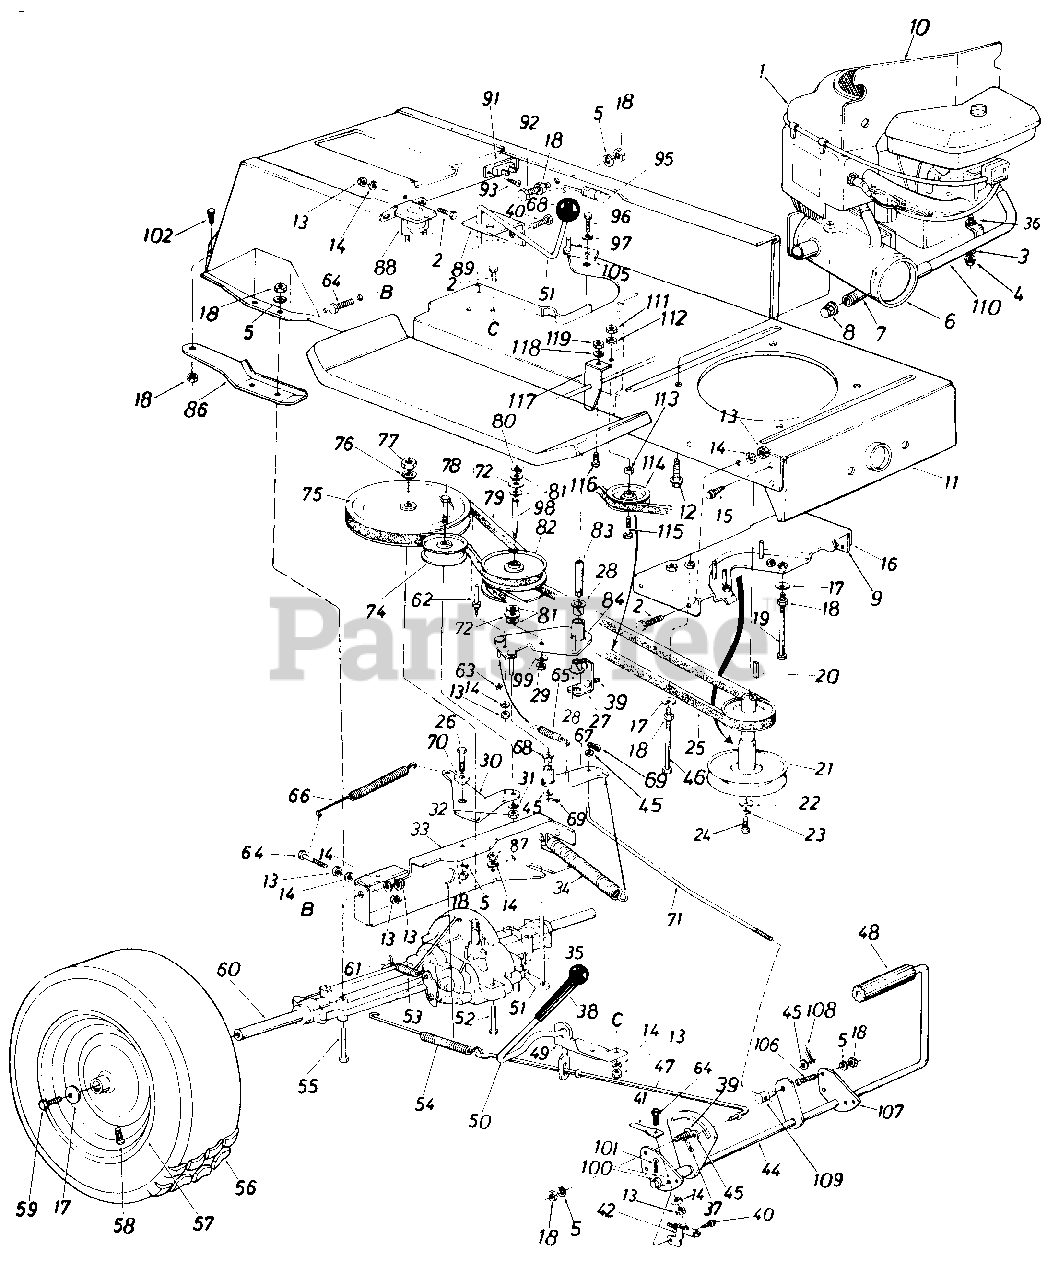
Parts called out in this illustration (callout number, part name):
1	Engine
2	Hex Bolt 1/4-20 x .62" Lg.*
3	Special L-Wash. 5/16" I.D.
4	Hex Nut 5/16-18 Thd.*
5	L-Wash. 5/16" I.D.*
6	Exhaust Muffler
7	Pipe Nipple
8	Cap Oil Drain
9	Brake Cable Brk't.
10	Heat Shield
11	Lower Frame Ass'y.
12	Hex Wash. Hd. TT-Tap Scr. 3/8-16 x 1.25" Lg.
13	Hex Nut 1/4-20 Thd.*
14	L-Wash. 1/4" I.D.*
15	Hex Wash. Hd. AB-Tap Scr. 5/16" x .75" Lg.
16	Belt Guard Brkt. Ass'y.
17	Bell-Wash. .345" I.D. x .88"
18	Hex Nut 5/16-18 Thd.*
19	Hex Bolt 5/16-18 x 4.00"*
20	Sq. Key 1/4 " x 1/4 " x 2.00"
21	Engine Pulley
22	Fl-Wash. 7/16" I.D. x 1.25"
23	L-Wash. 7/16" I.D.*
24	Hex Bolt 7/16-20 x 1.50" Lg.
25	Variable-Speed Belt .715 x 53" Lg.
26	Hex Bolt 5/16-18 x .75" Lg.*
27	Bearing Shaft Bracket
28	Flanged Nyliner Brg. 5/8" I.D. x .88 " Lg.
29	Hex Nut 3/8-24 Thd.*
30	Idler Bracket
31	L-Wash. 3/8" I.D.*
32	Hex Nut 3/8-24 Thd.*
33	Transaxle Support Brkt.
34	Ext. Spring .94" O.D. x 6.7
35	Cotter Pin 1/8" Dia. x 1.0"*
36	Fl-Wash. .34" I.D. x .62" O.D. x .033
37	Cotter Pin 3/32" Dia. x 1.0"*
38	Grip Black
39	Truss Mach. Scr. 5/16-18 x .75" Lg.
40	Hex Wash. Hd. Self-Tap Scr. 1/4-20 x .50" Lg.
41	Switch Actuator
42	Safety Switch
44	Clutch & Brake Pedal Ass'y.
45	Fl-Wash.
46	Hex Bolt 5/16-18 x 4.5"*
47	Brake Rod
48	Foot Pad
49	Brake Lever Bracket
50	Hill Holder Brake Handle
51	Shift Lever Ass'y.
52	Hex Bolt 1/4-28 x 1.75" Lg.*
53	Ext. Spring .38" O.D. x 2.5"
54	Ext. Spring .59" O.D. x 7.08"
55	Hex Bolt 5/16-18 x 2.50"*
58	Air Valve
59	Hex Bolt 5/16-24 x .75" Lg.*
60	Transaxle Complete
61	Brake Return Spring Anchor
62	Belt Guard Pin 1/4-20 Thd.
63	Cap Speed Nut 1/4" Dia.
64	Hex Bolt 1/4-20 x 1.0" Lg.*
65	Ext. Spring .50" Dia.
66	Ext. Spring .56" O.D. x 5.96"
67	Variable Speed Torque Brkt. Ass'y.
68	Flanged Bearing
69	Cotter Pin 3/32" Dia.*
70	Shoulder Spacer .500" Dia. x .27" Lg.
71	Speed Control Link
72	Truss Bearing .56 Dia. x 1.25"
72	Ball Knob
74	Fl-ldler Pulley 3.25" x 1.0"
75	11/16" "V"-Pulley 8.0" O.D. x .501" I.D.
76	L-Wash. 1/2" I.D.
77	Hex Jam Nut 1/2-20 Thd.*
78	Hex Bolt 3/8-24 x 1.50" Lg.*
79	Variable Speed Belt .715 x 44" Lg.
80	Snap Ring .56" Dia.
81	Fl-Wash .
82	Variable Speed Pulley Ass'y. 5" O.D.
83	Bearing Shaft
84	Variable Speed Brkt. Ass'y.
84	Belt Guard Pin 1/4" Dia. x 1.68" Lg.
86	Transaxle Support Brkt. R.H.
86	Transaxle Support Brkt. L.H.
87	Hex Nut 1/4-28 Thd.
88	Solenoid
89	Shift Lever Bracket
91	Circuit Breaker
92	Hex Bolt 5/16-18 x 1.25" Lg.
93	Truss Hd. Phil. Scr. #10 x 1/2" Lg.
95	Ext. Spring .99" O.D. x 11.0"
96	Hex Bolt 3/8-24 x .75" Lg.*
97	Bell-Wash. .38" I.D. x .88"
98	Shaft .56" Dia. x 3.875" Lg.
99	Bell-Wash. .39" I.D. x 1.12"
100	Fl-Wash.
101	Cotter Pin
102	Hex Wash. Hd. Scr. 5/16-18 x .62" Lg.
102	Fl-Wash. .32" I.D. x 1.25"
105	Belt Guard
106	Truss Mach. Scr. 5/16-18 x .75" Lg.*
107	Pedal Bracket
108	Hairpin Cotter 118" Dia.
109	Ferrule
110	Inlet Tube Ass'y.
111	Hex Nut 3/8"-16 Thd.*
112	L-Wash. 3/8" I.D.*
113	Fl-Wash. .390" I.D. x 1.12" O.D. x .187
114	Fl-ldler w/ Flanges 2.750
115	Hex Bolt 3/8-16 x 2.00" Lg.*
116	Hex Bolt 1/4-20 x .62" Lg.*
117	Spring Hanger Bracket
118	L-Wash. 1/4" I.D.*
119	Hex Nut 1/4-20 Thd.*
